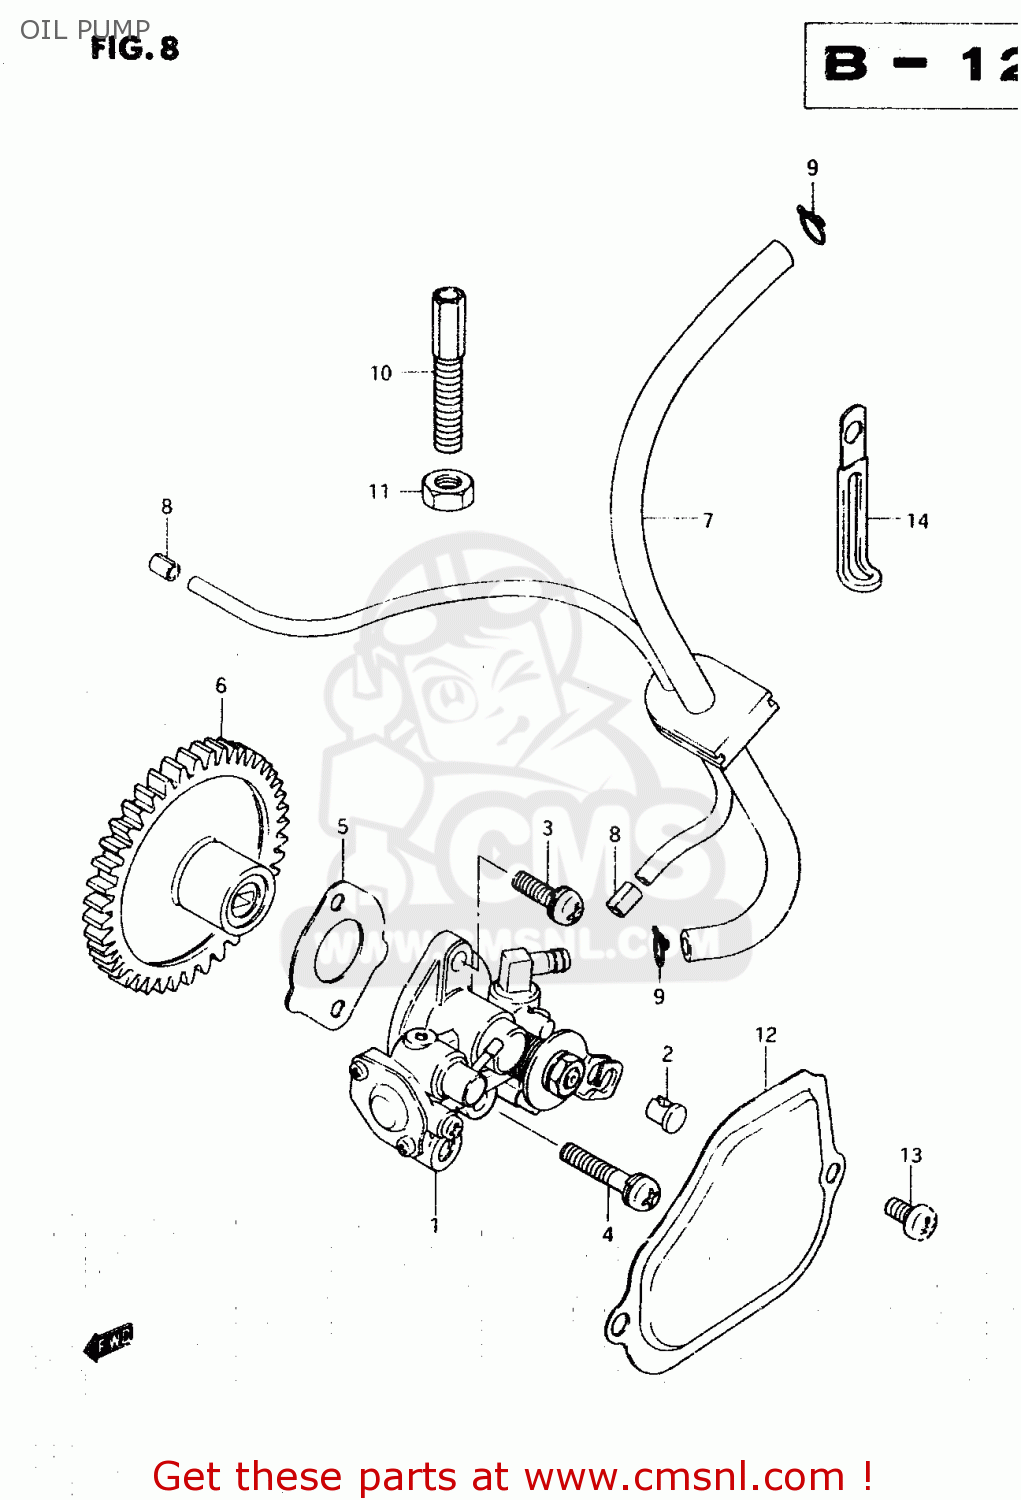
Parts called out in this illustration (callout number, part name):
1	PUMP ASSY,OIL
2	TERMINAL,CABLE
3	SCREW
4	SCREW
5	GASKET,OIL PUMP (NAS)
6	GEAR,OIL PUMP DRIVEN(NT:37)
7	HOSE SET,OIL NO.2
8	CLIP
9	CLIP
10	BOLT
11	NUT
12	CAP,OIL PUMP INSPECTION
13	SCREW
14	CLAMP
